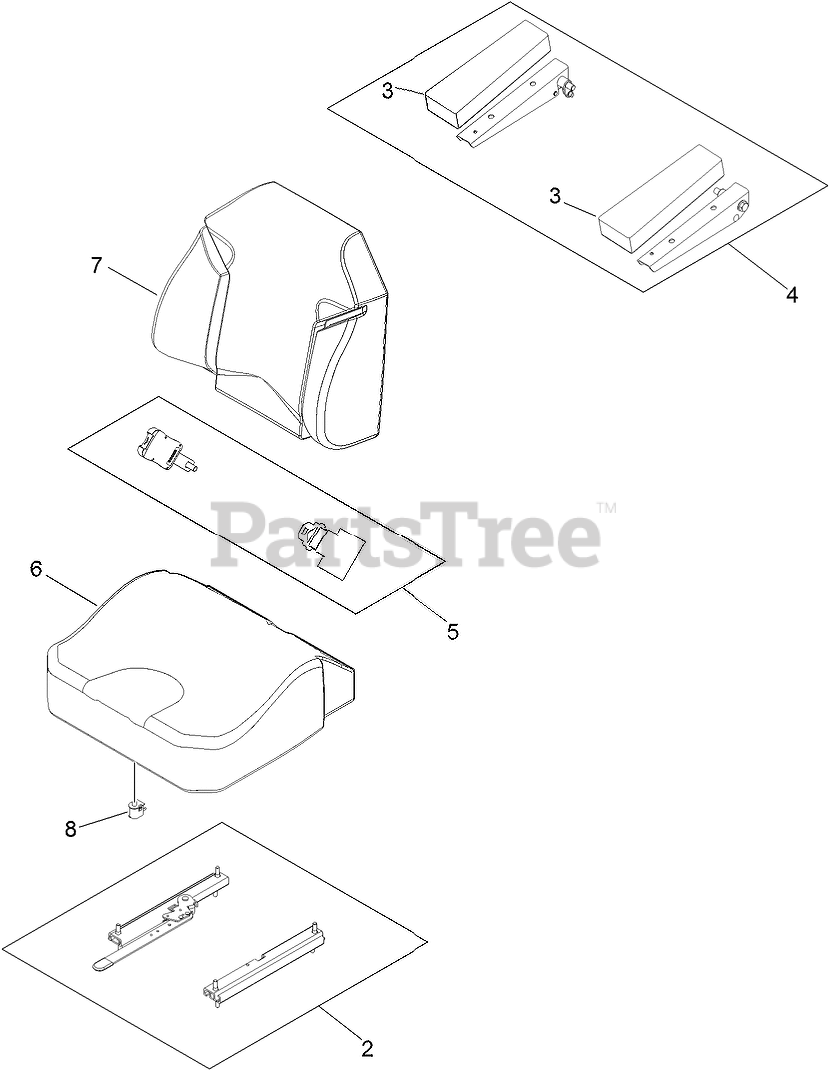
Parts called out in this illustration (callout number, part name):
2	SEAT TRACK SET
3	ARM REST PADS SET
4	ARM REST KIT
5	SEAT BELT KIT
6	COVER-CUSHION
7	COVER-BACK
8	SWITCH-BAIL
